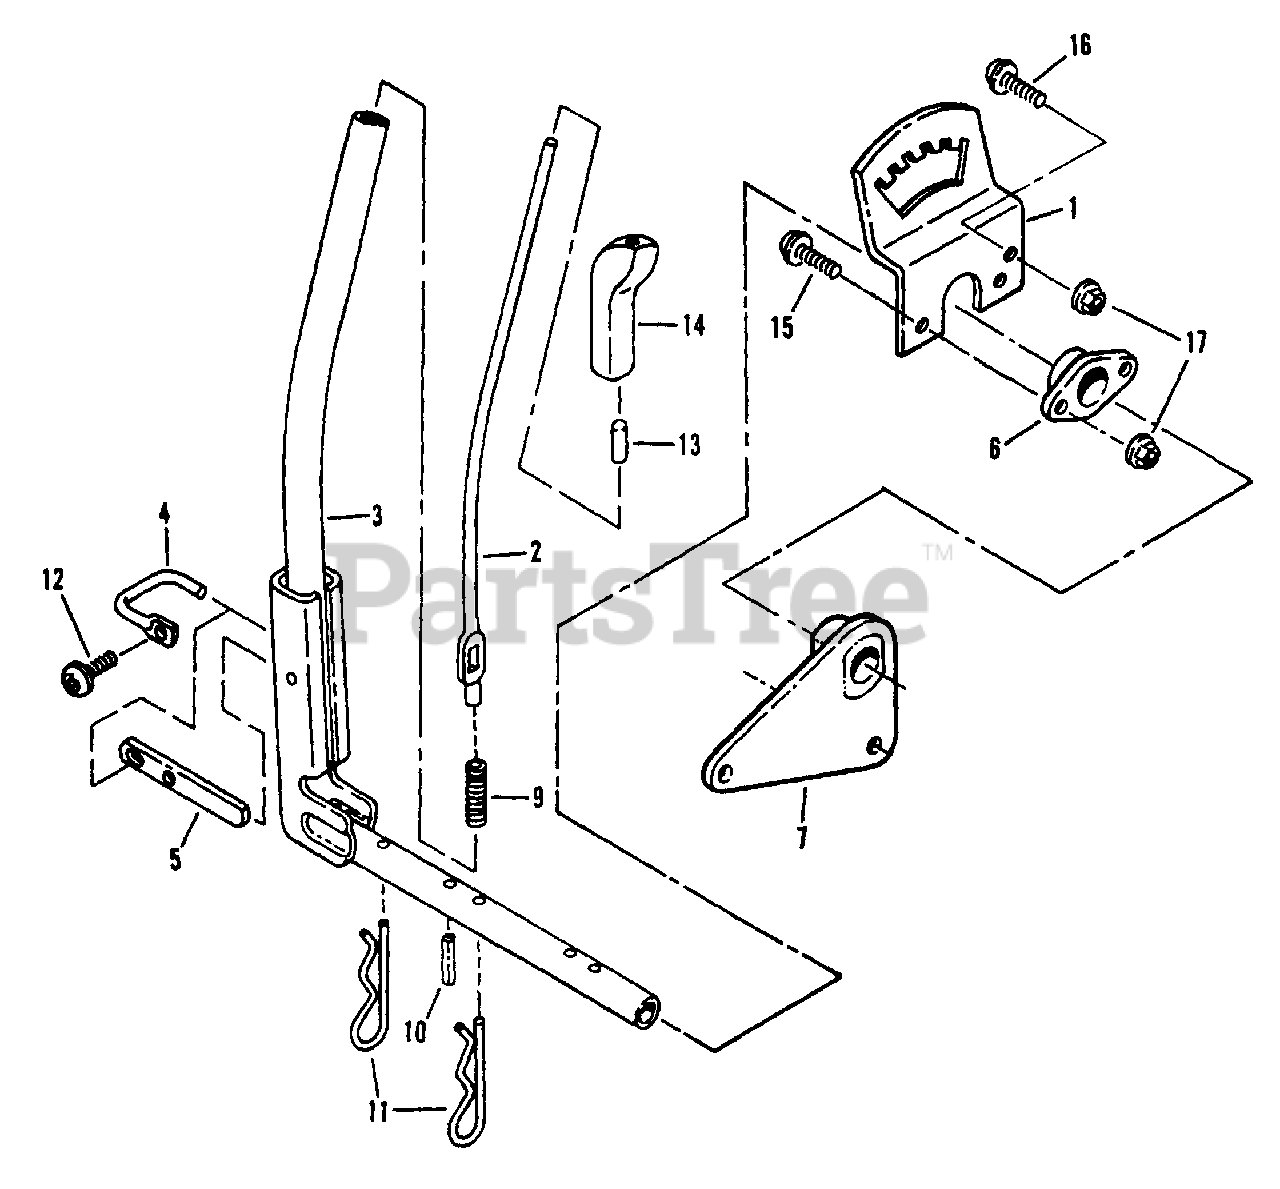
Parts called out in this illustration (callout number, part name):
1	QUADRANT, Lift Lever
2	ROD, Lift Lever
3	STRUCTURE, Lift Lever
4	LATCH, Pivot
5	DETENT, Latch
6	PIVOT, Lift Lever
7	BELLCRANK, Lift Structure
10	PIN, 1/4 x 1-1/8 Dowel
11	PIN, 5/32 x 2-5/8" Hair
12	SCREW, 1/4-20 x 5/8" Truss Head (Torx)
13	CAP, Lever Rod
14	KNOB, Lift Lever
15	SCREW, 5/16-18 x 7/8" Truss Head (Torx)
16	SCREW, 5/16-18 x 5/8" Truss Head (Torx)
17	NUT, 5/16-18 Hex Flange Lock
